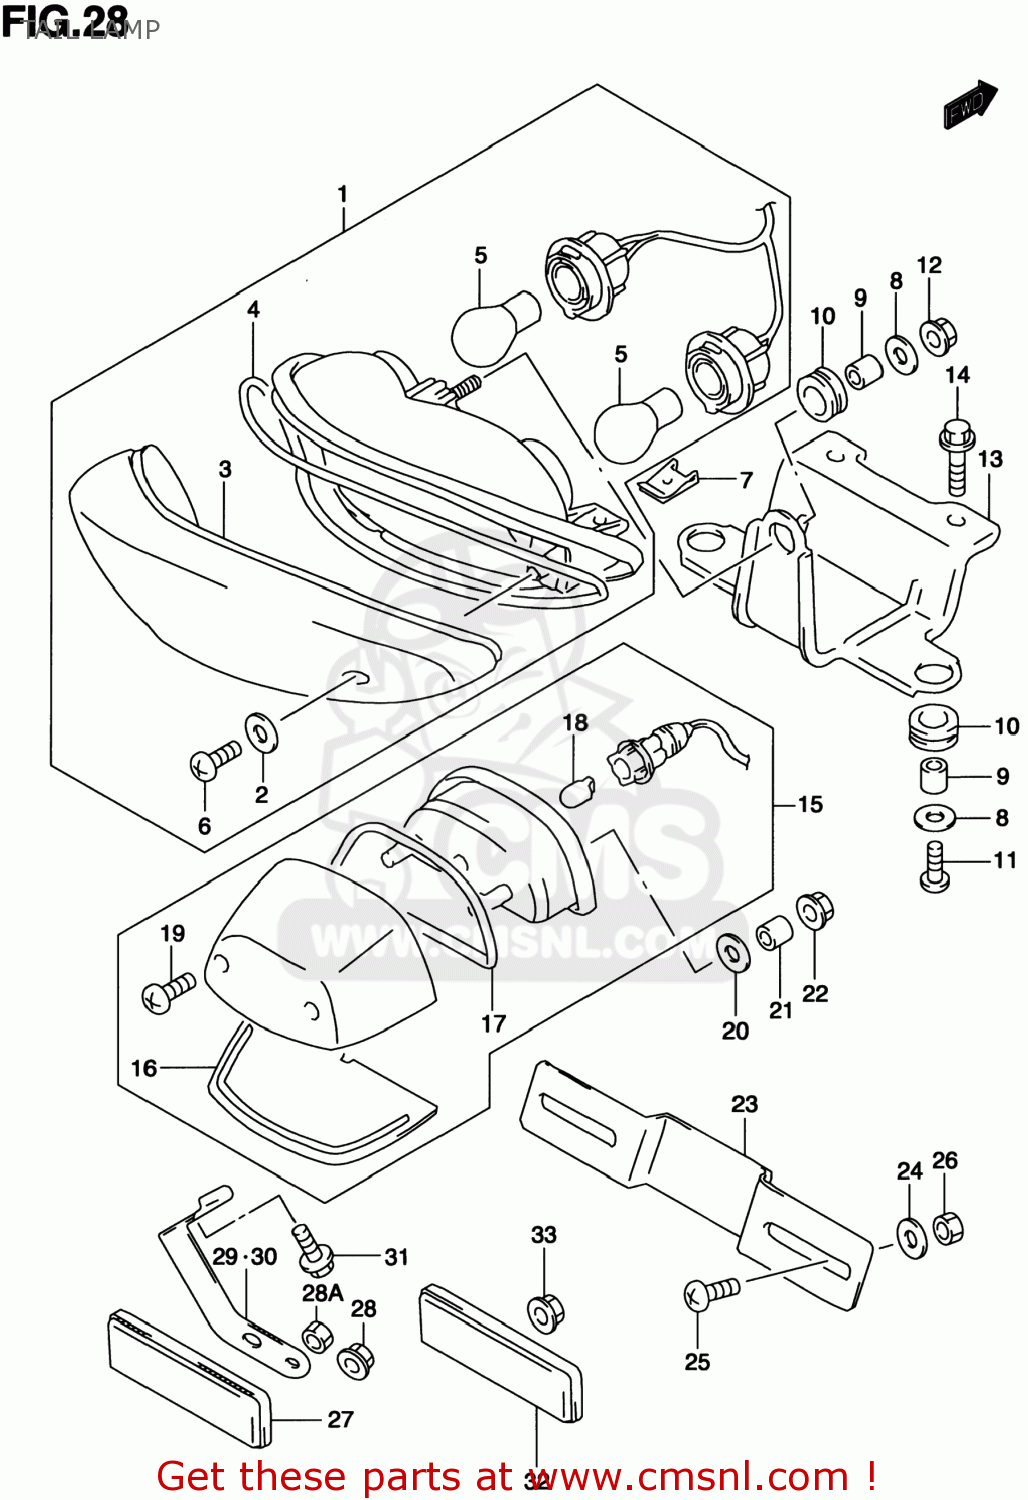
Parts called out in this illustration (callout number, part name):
1	LAMP ASSY,RR COMBINATION
2	GASKET (NAS)
3	LENS
4	GASKET (NAS)
5	BULB(12V21/5W)
6	SCREW
7	NUT
8	WASHER(6.5X20X1.6)
9	SPACER(6.5X10X9)
10	CUSHION
11	SCREW
12	NUT
13	BRACKET,RR COMBINATION LAMP
14	BOLT
15	LAMP ASSY,LICENSE
16	LENS
17	GASKET (NAS)
18	BULB(12V5W)
19	SCREW
20	WASHER(6.5X20X1.6)
21	SPACER(5.5X9.5X11.5)
22	NUT
23	BRACKET,LICENSE PLATE
24	WASHER(6.5X20X1.6)
25	SCREW 6X12
26	NUT
27	REFLECTOR ASSY,RR
28	NUT
28A	NUT
29	BRACKET,RR SIDE RR,R
30	BRACKET,RR SIDE RR,L
31	BOLT
32	REFLECTOR ASSY,RR
33	NUT
